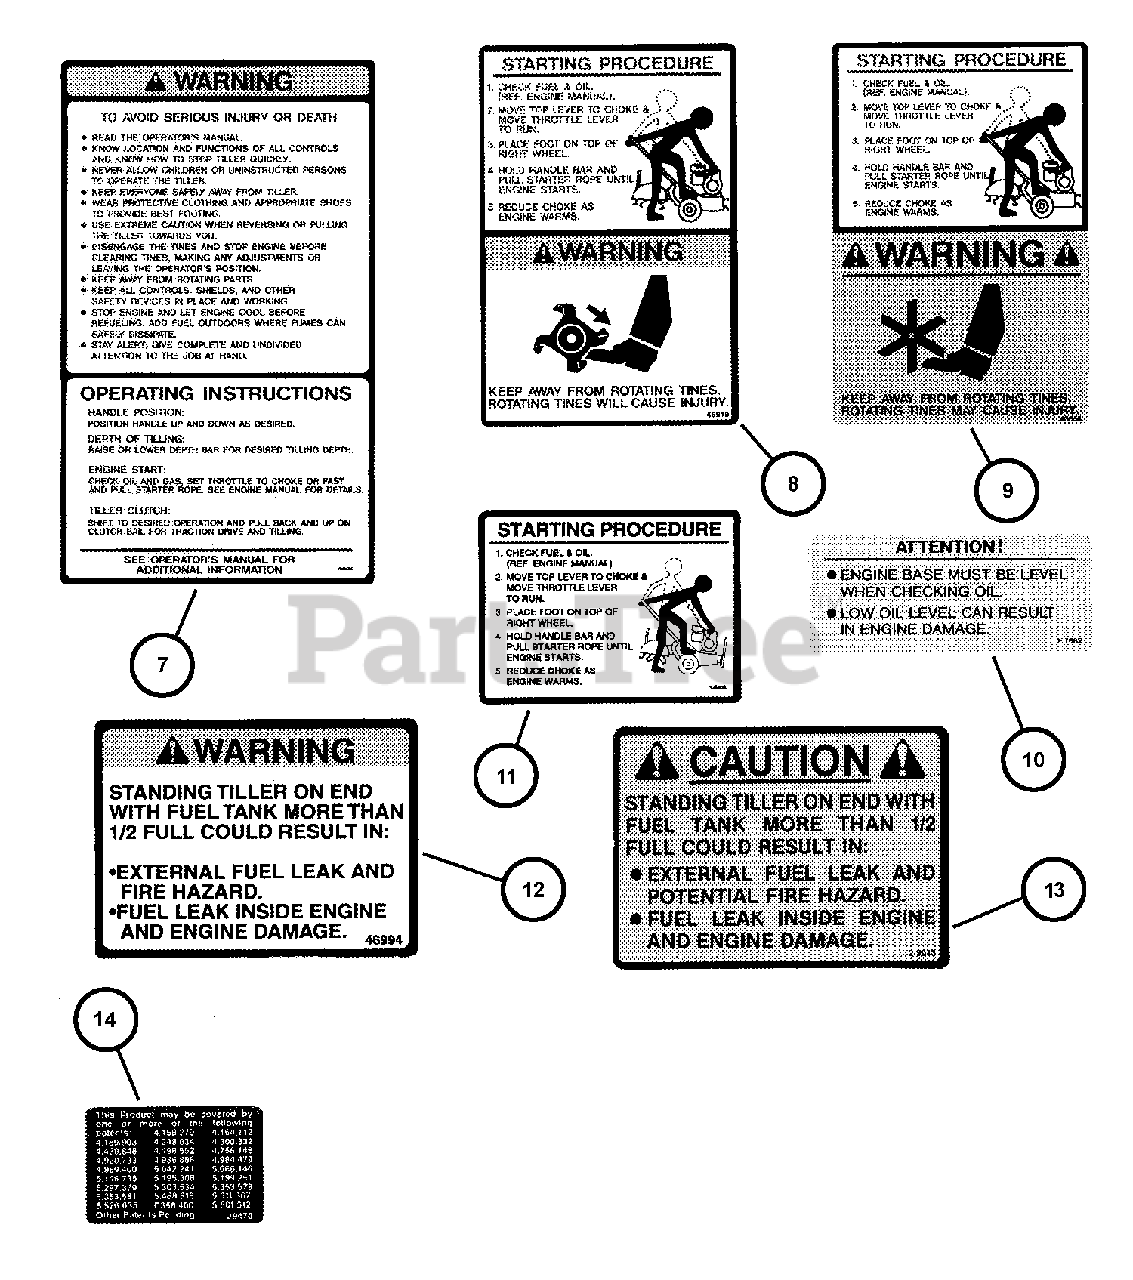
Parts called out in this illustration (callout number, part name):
7	DECAL, Warning/Instructions
8	DECAL, Starting and Warning
9	DECAL, Warning/Starting Procedure
10	DECAL, Engine Oil
11	DECAL, Starting Procedure
12	DECAL, Caution (Standing on end)
13	DECAL, Caution (Standing on end)
14	DECAL, Patent Numbers
